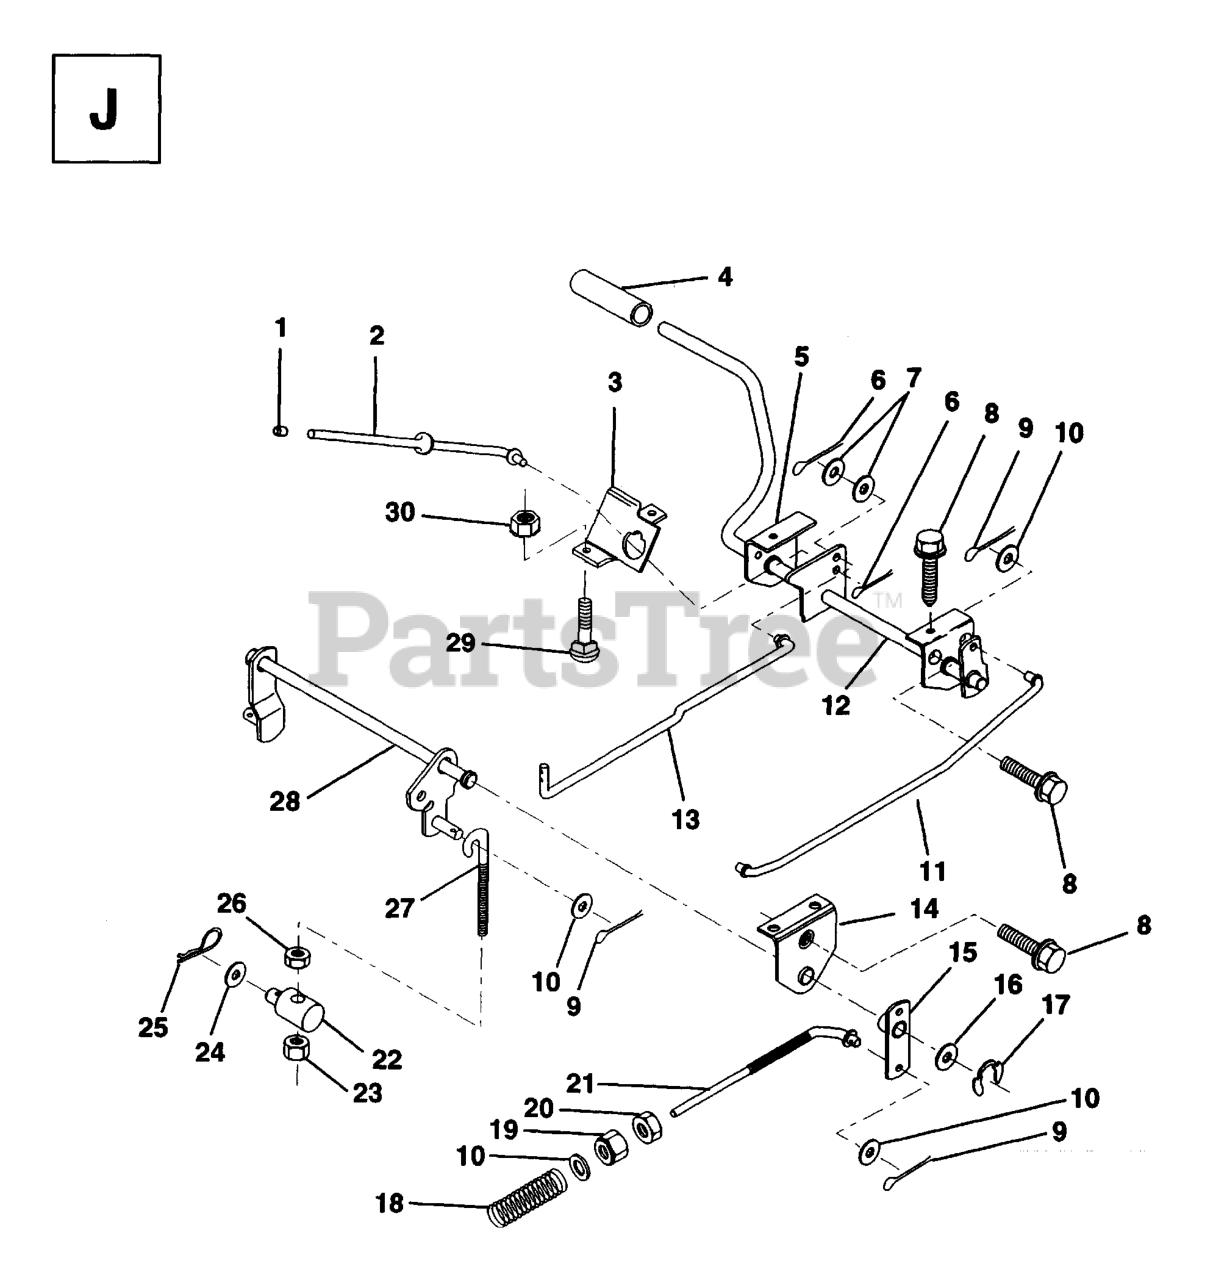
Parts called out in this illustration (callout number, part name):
1	PLUNGER CAP
2	ROD,PARK BRAKE
3	BRKT,PARK BRAKE
4	FOOT PEDAL COVER
5	BRKT,CLU PEDAL LH
6	COTTER PIN
8	Screw 5/16-18 x 1/2 Hex, Self Tapping 5/16-18 x 1/2
9	COTTER PIN
10	WASHER
11	ROD,FRT BRAKE
12	CLUTCH/BRAKE PEDAL ASSY
13	ROD,CLUTCH
14	BRKT,LIFT SHAFT
15	BRAKE PIVOT ARM
17	Ring, Klip Truarc #5304-75
18	SPRING ROD LT
19	NUT
20	NUT
21	ROD REAR BRAKE
22	TRUNION LIFT
24	WASHER
25	COTTER PIN
26	LOCKNUT
27	LINK.MOWER.REAR
28	LIFT, REAR
29	BOLT.CARR.SQNK.5/16-18UNC.X3/4
30	NUT
